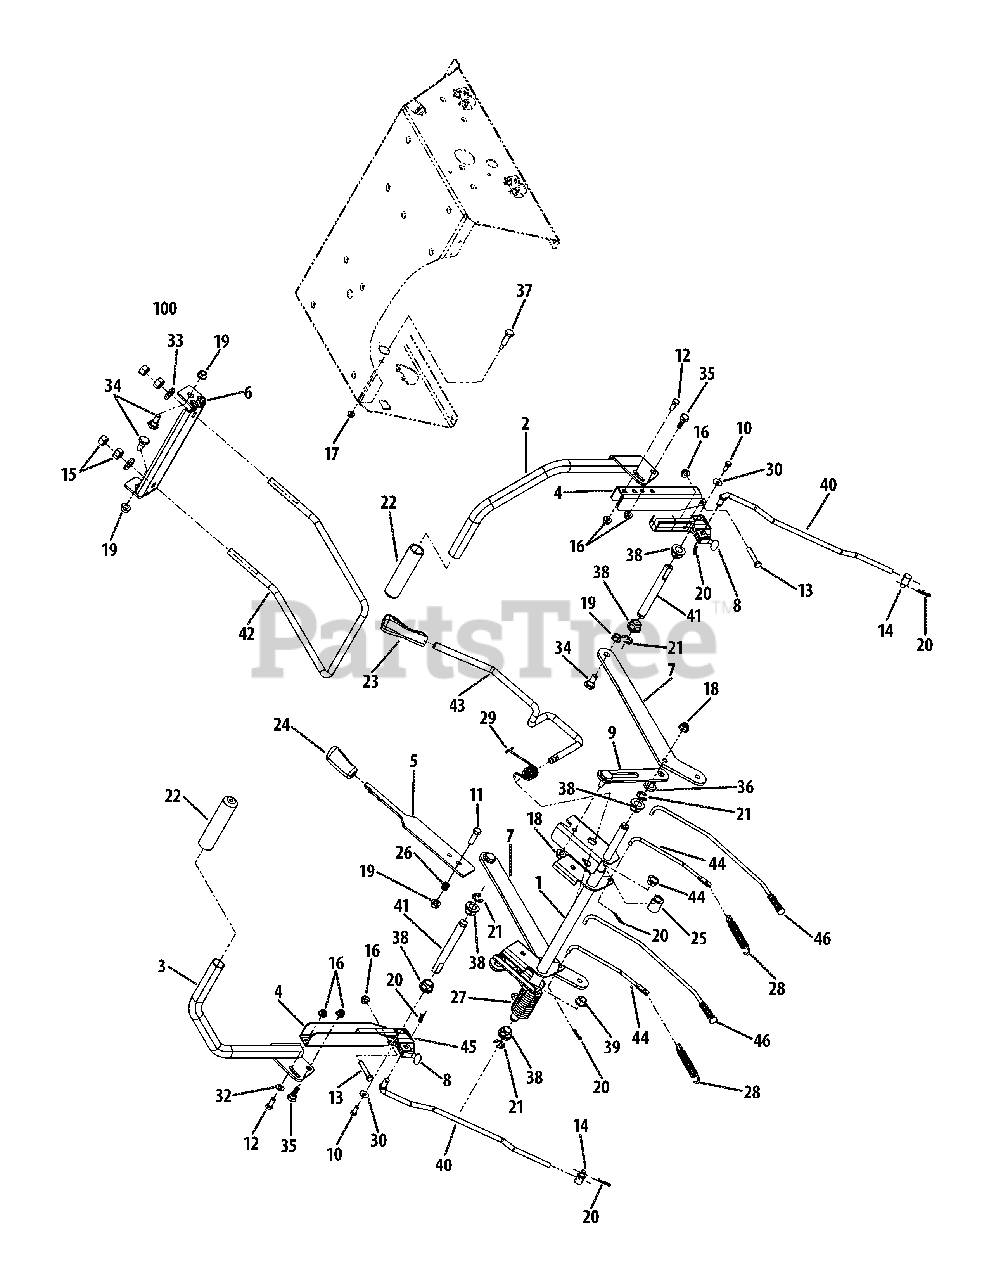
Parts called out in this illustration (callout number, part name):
4	Lapbar Pivot Bracket
8	Switch Actuator Bracket
10	Hex Lock Screw, 1/4-20 x .625
11	Hex Screw, 3/8 -16 x 1.25
12	Hex Screw, 5/16-18 x .75
13	Hex Screw, 5/16-18 x 1.75
14	Ferrule, 3/8 -24 x .375
15	Hex Nut, 1/2-13
16	Flange Lock Nut, 5/16-18
17	Flange Lock Nut, 1/4-20
18	Flange Lock Nut, 3/8 -16
19	Flange Lock Nut, 3/8-16
20	Cotter Pin, .072 x 1.13
21	E-Ring, .625
22	Grip, 1.0 x 5.0
23	Handle Grip, 1/2
24	Selector Handle
25	Spacer, .62 x 1.00
26	Compression Spring, .50 x .50
27	Torsion Spring, 1.194
28	Extension Spring, .59 x 4.00
29	Spring, Torsion RZT
30	Bell Washer, .265 x .75 x .062
31	Flat Washer, .510 x 1.00 x .060
32	Flat Washer, .344 x .688 x .065
33	Flat Washer, .531 x 1.062 x .134
34	Shoulder Screw, .496 x .336 x 3/8-16
35	Shoulder Screw, .437 x .268 x 5/16-18
36	Shoulder Screw, .500 x .434
37	Shoulder Screw, .374 x 1.16
38	Hex Flange Bearing
39	Flange Bearing, .626 x .938 x .344
40	Lapbar Control Rod
41	Shaft Control
42	Deck Lift Front Hanger Rod
43	Deck Lift Handle Rod
44	Brake Rod
